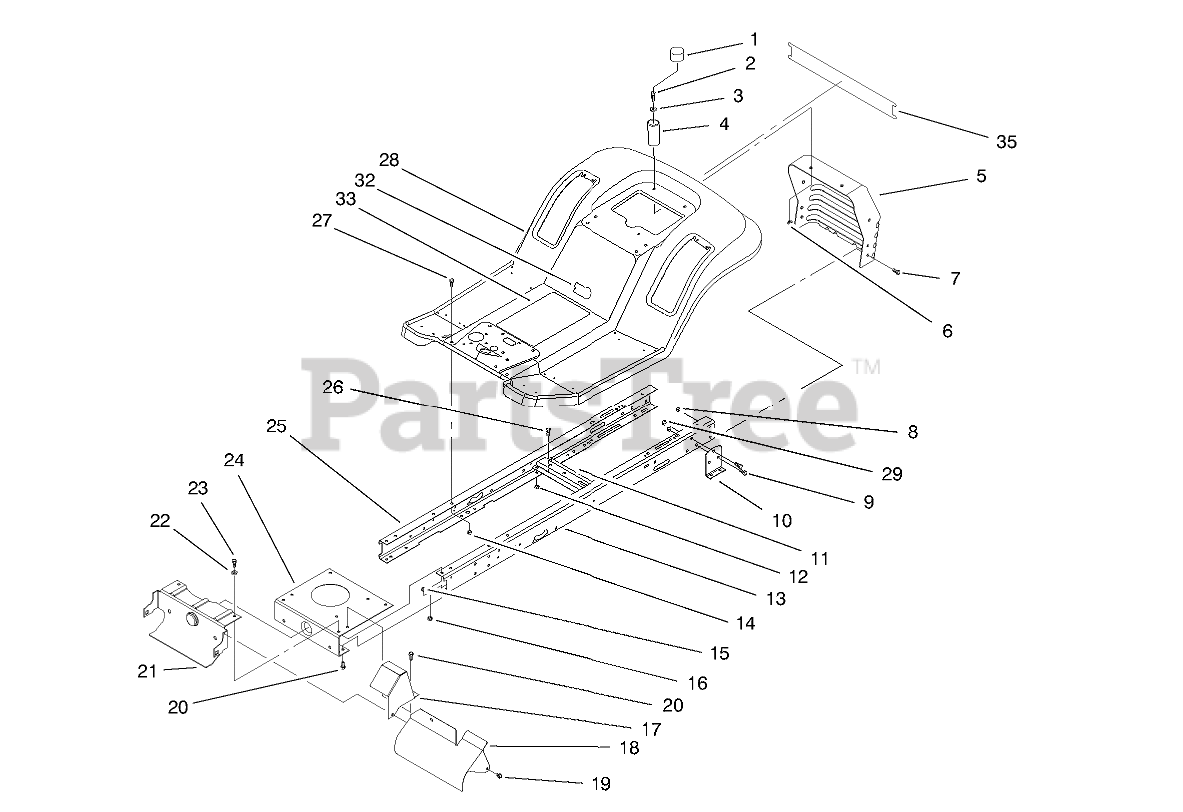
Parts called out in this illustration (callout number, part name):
1	CAP-PROTECTOR
2	SCREW-HH
3	WASHER-PLAIN
4	SPRING-COMPRESSION
5	Panel-Rear
6	NUT-LOCK, NI
7	SCREW-HH
8	NUT-LOCK, NI
9	SCREW-HH
10	BRACKET-TRANSAXLE, MOUNTING
11	BRACKET-IDLER PIVOT
12	NUT-LOCK, NI
13	Frame Rail-LH
14	NUT-LOCK, NI
15	NUT-LOCK, NI
16	NUT-LOCK, NI
17	SHIELD-EXHAUST PIPE
18	SHIELD-MUFFLER
19	SCREW-HWHTF
20	SCREW-HH
21	Support-Front Axle
22	WASHER-PLAIN
23	SCREW-HH
24	PLATE-MOUNTING, ENGINE
25	Frame Rail-RH
26	SCREW-HH
27	SCREW-HH
28	Body-Rear
29	NUT-LOCK, NI
32	DECAL - USA
33	DECAL - INSTRUCTION
35	DECAL - REAR BODY
